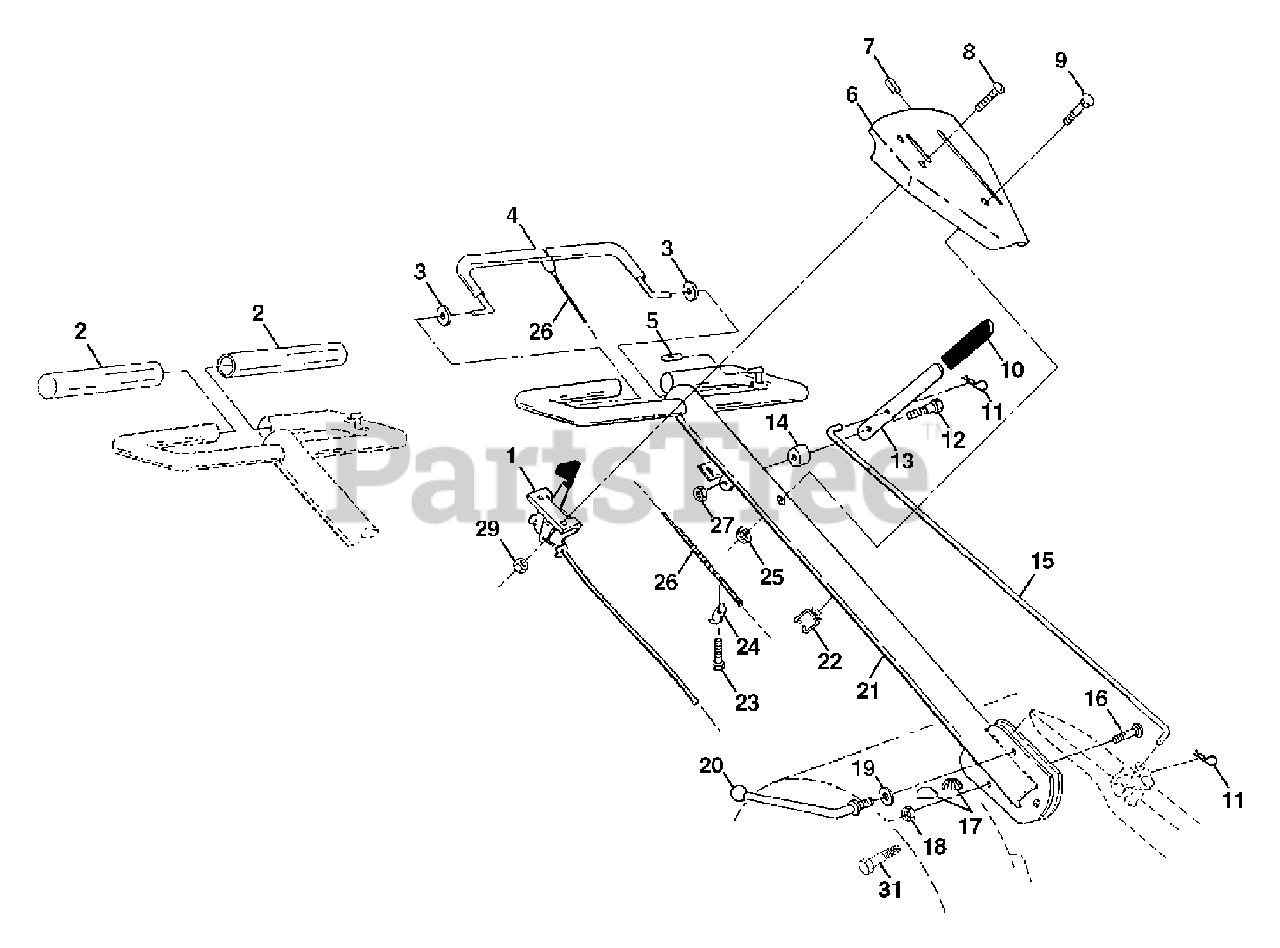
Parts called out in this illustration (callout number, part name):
1	Control, Throttle
2	Grip, Handle
3	Grommet Handle
4	Bar Assembly, Control
6	Panel, Control
7	Bushing Split
8	Screw, Truss Hd. #10-24 Unc x 1/2
9	Bolt 5/16-18 x 2.50
10	Grip, Handle
11	Clip, Hairpin
12	Bolt, Shoulder
13	Handle, Shift
14	Grommet, Rubber
15	Rod, Shift
16	Bolt, Carriage 3/8-16 x 1 Gr. 5
17	Lock, Handle
18	Nut, Crownlock 3/8-16 Unc
19	Washer 13/32 x 1 x 11 Ga.
20	Lever, Lock, Handle
21	Handle
22	Clip Cable
23	Screw, Hex Washer Hd. Slotted #10-24 x 1/2
25	Nut Lock Hex Flange
26	Cable, Clutch
27	Nut Hex Flange 1/4-20 Unc
29	Nut, Keps #10-24 Unc
31	Bolt, Pivot
